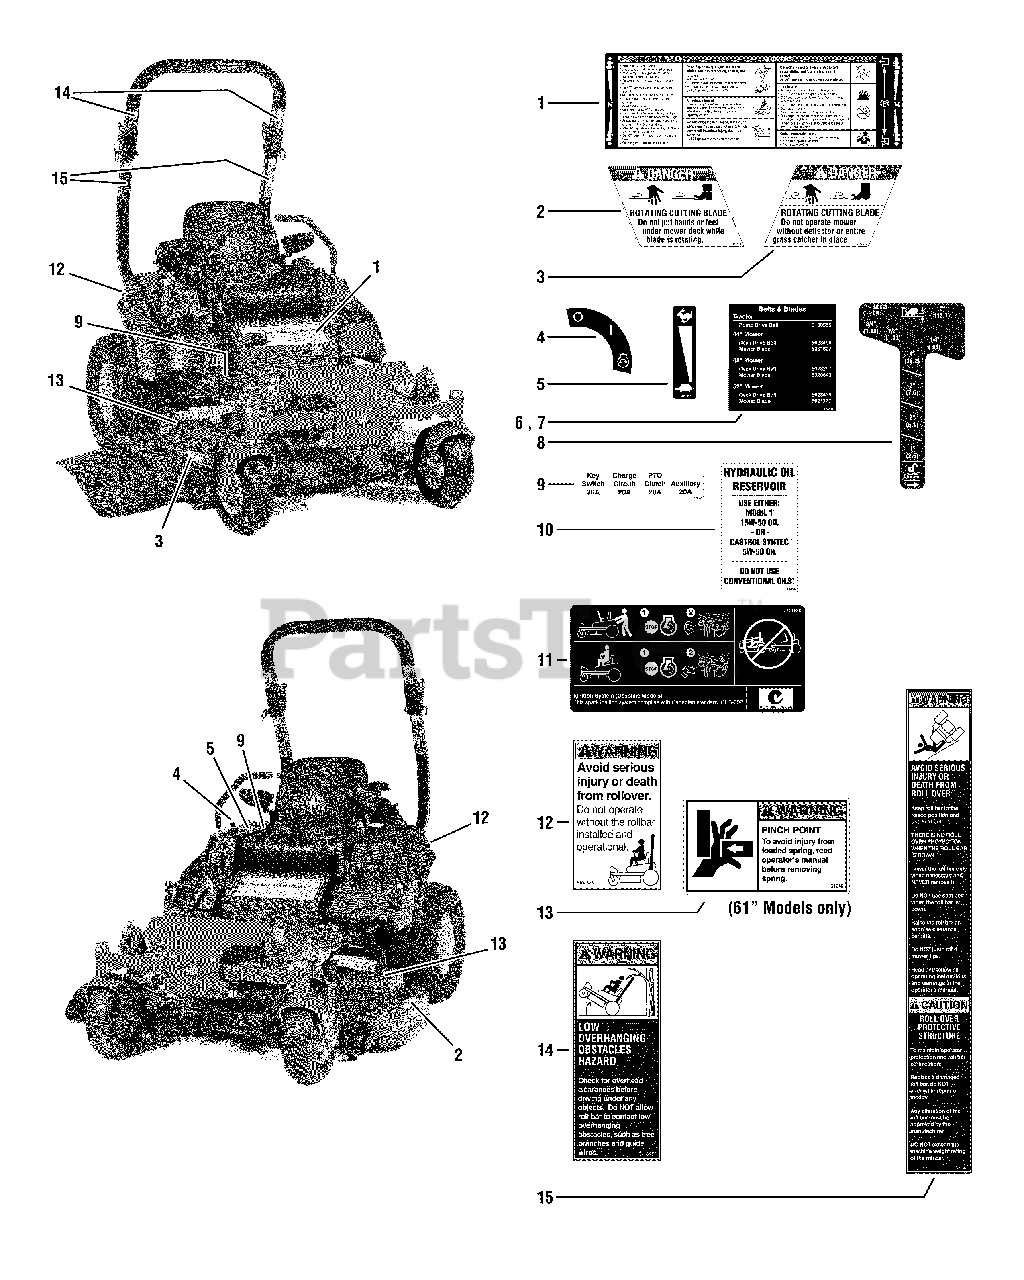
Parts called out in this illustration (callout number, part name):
1	DECAL, MAIN
2	DECAL-DANGER DO NOT OPERATE W/O DEFLECTR
3	DECAL-DANGER DO NOT PUT HAND/FEET IN MWR
4	DECAL-IGNITION SWITCH
5	DECAL, THROTTLE CONTROL
6	* DECAL, BELT & BLADE, IS1500Z
6	DECAL, BELT & BLADE
7	DECAL, BELT & BLADE
8	DECAL-HEIGHT CITATION
9	DECAL, FUSE LOCATION
10	DECAL, OIL RESERVOIR
11	DECAL, CZT HYRDO RELEASE
12	DECAL, WARNING ROLL BAR
13	DECAL, PINCH POINT
14	DECAL, WARNING OVERHANG, ROPS
